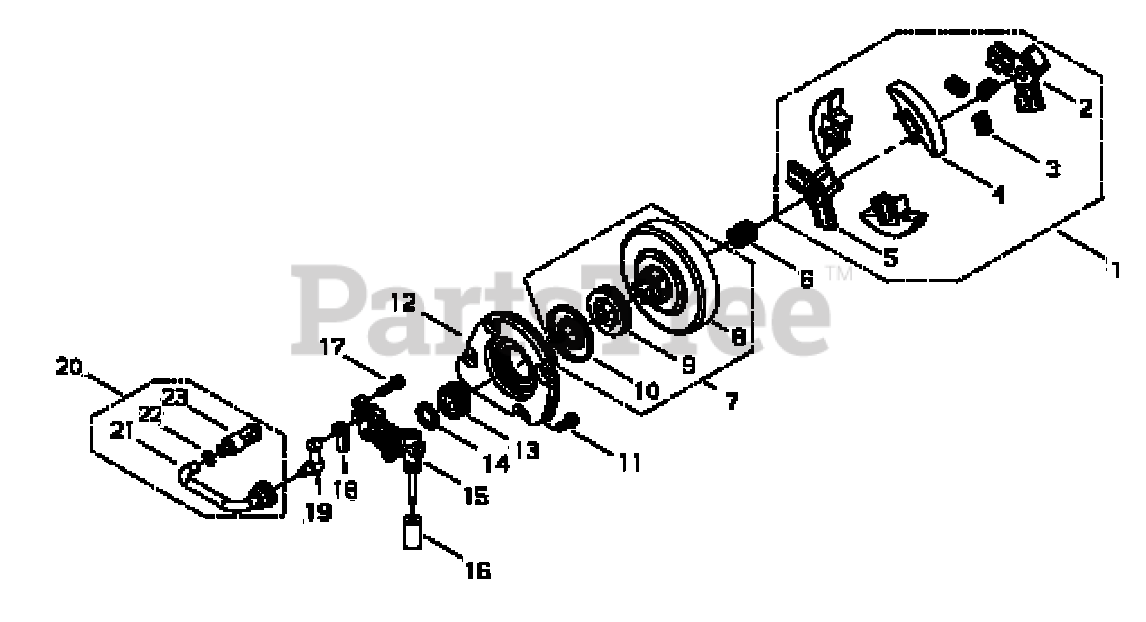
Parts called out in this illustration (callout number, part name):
1	CLUTCH ASSY
2	HUB, CLUTCH - OUTER
3	SPRING, CLUTCH
4	SHOE, CLUTCH
5	HUB, CLUTCH - INNER
6	BEARING, NEEDLE
7	CLUTCH DRUM ASSY
8	DRUM, CLUTCH
9	SPROCKET, RIM
10	COVER
11	SCREW
12	COVER, PUMP
13	GEAR
14	PLATE, THRUST
15	OIL PUMP ASSY
16	FILTER
17	SCREW - 4X16
18	GASKET, PUMP
19	CONNECTOR, PIPE
20	OIL PIPE ASSY
21	PIPE - OIL
22	CLIP
23	FILTER, OIL
